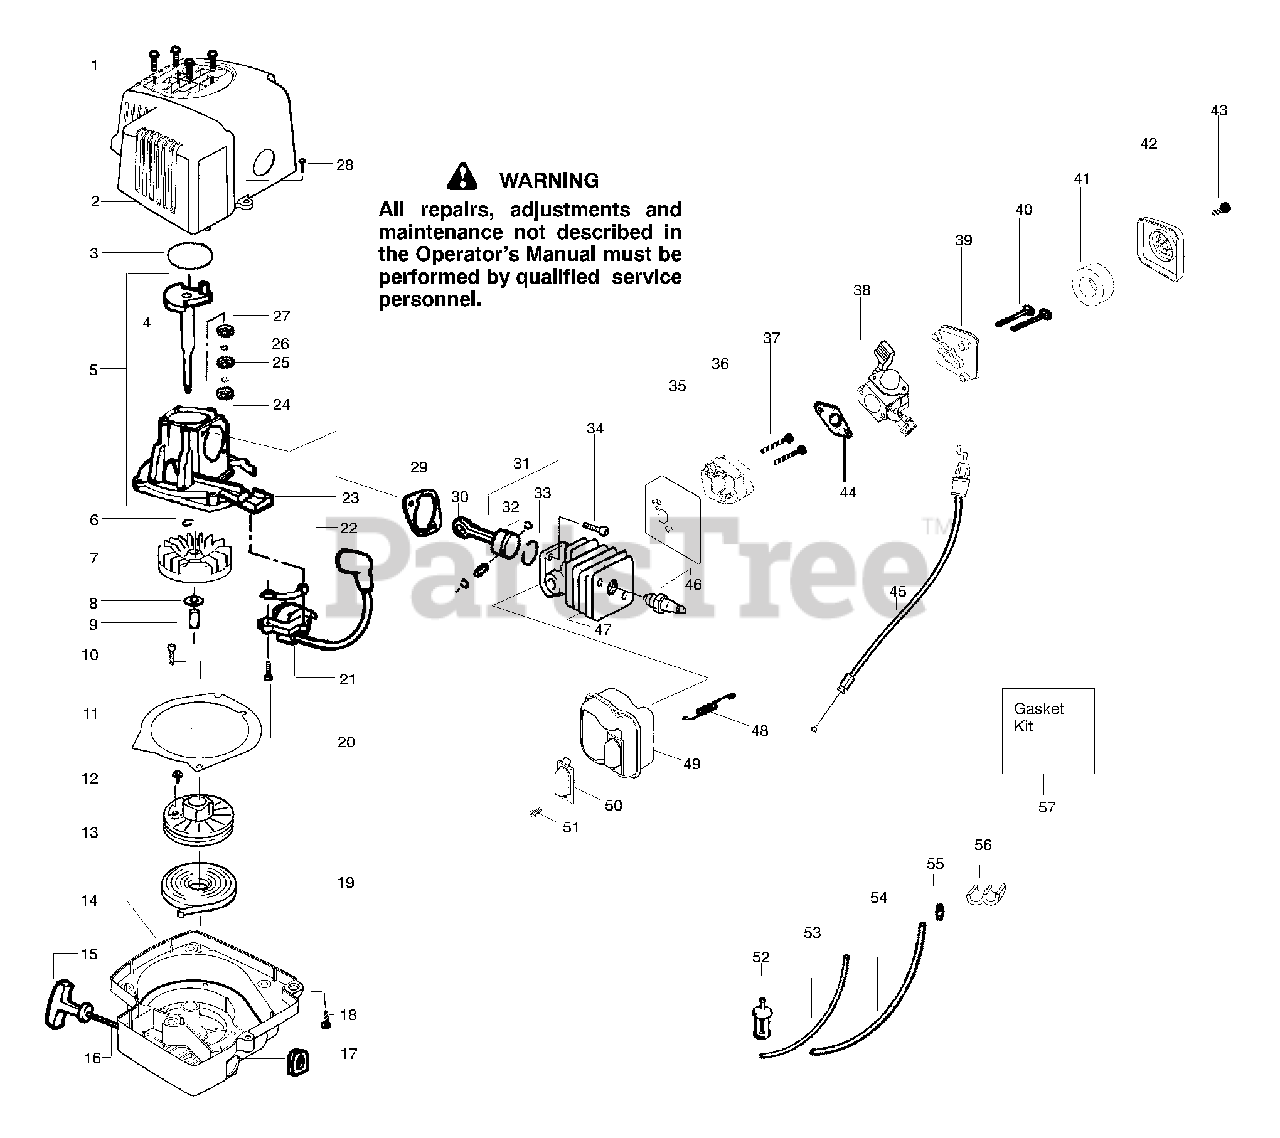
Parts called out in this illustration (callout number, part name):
2	Assy-Shroud/H'shield
3	O-Ring-Shrd/C'case
4	Assy-Crankshaft
5	Assy-C/case-C/shaft
6	Ring-Retainer-C'shaft
7	Assy-Flywheel
8	Washer-Flat
9	Spacer-Flywheel
11	Plate-Baffle
13	Kit-Starter Pulley
14	Assy-Fan Housing
15	Handle-Starter
16	Kit-Rope
17	Grommet-Ignition Module
18	Screw-(f/hsg to shrd)
19	Spring-Starter
21	Ignition Module
22	Spacer-Ign. Module
23	Assy-Crankcase
24	Bearing-Outer
25	Seal-Crankcase
26	Ring-Retainer-C'case
27	Bearing-Inner
29	Gasket-Cylinder
30	Assy-Connecting Rod
31	Kit-Piston
32	Retainer-Piston Pin
33	Ring-Piston
35	Gasket-Cyl./Carb. Adapt.
36	Adapter-Carburetor
38	Kit-Carburetor Ass'y. (C1U-W13)
38	Kit-Carburetor Ass'y. (C1U-W13A)
41	Air Filter Foam
42	Air Filter Cover
44	Gasket-Carburetor
45	Assy-Throttle Cable
46	Spark Plug (RCJ-7Y)
47	Kit-Cylinder
48	Spring-Muffler
49	Kit-Muffler
50	Kit-Spark Arrestor
51	Screw
52	Assy-Pick-up
53	Kit-Fuel Line(small)
54	Kit-Fuel Line(large)
55	Fitting-Fuel Line
56	Clip-Retainer
57	Kit-Gasket
